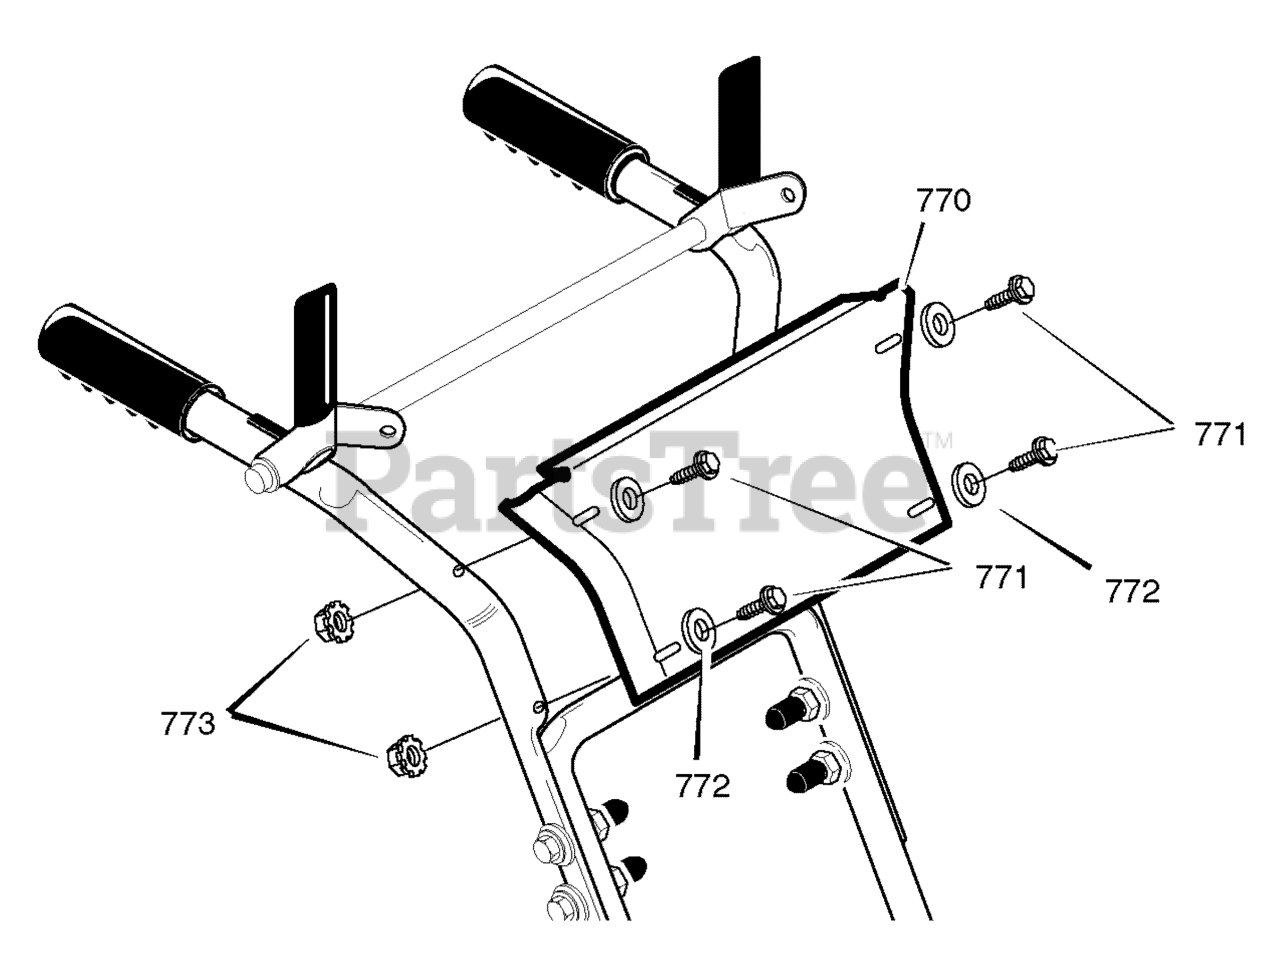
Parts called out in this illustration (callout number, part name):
771	BOLT, CARRIAGE
772	WASHER
773	NUT, 1/4-20 NYLOCK YZ
